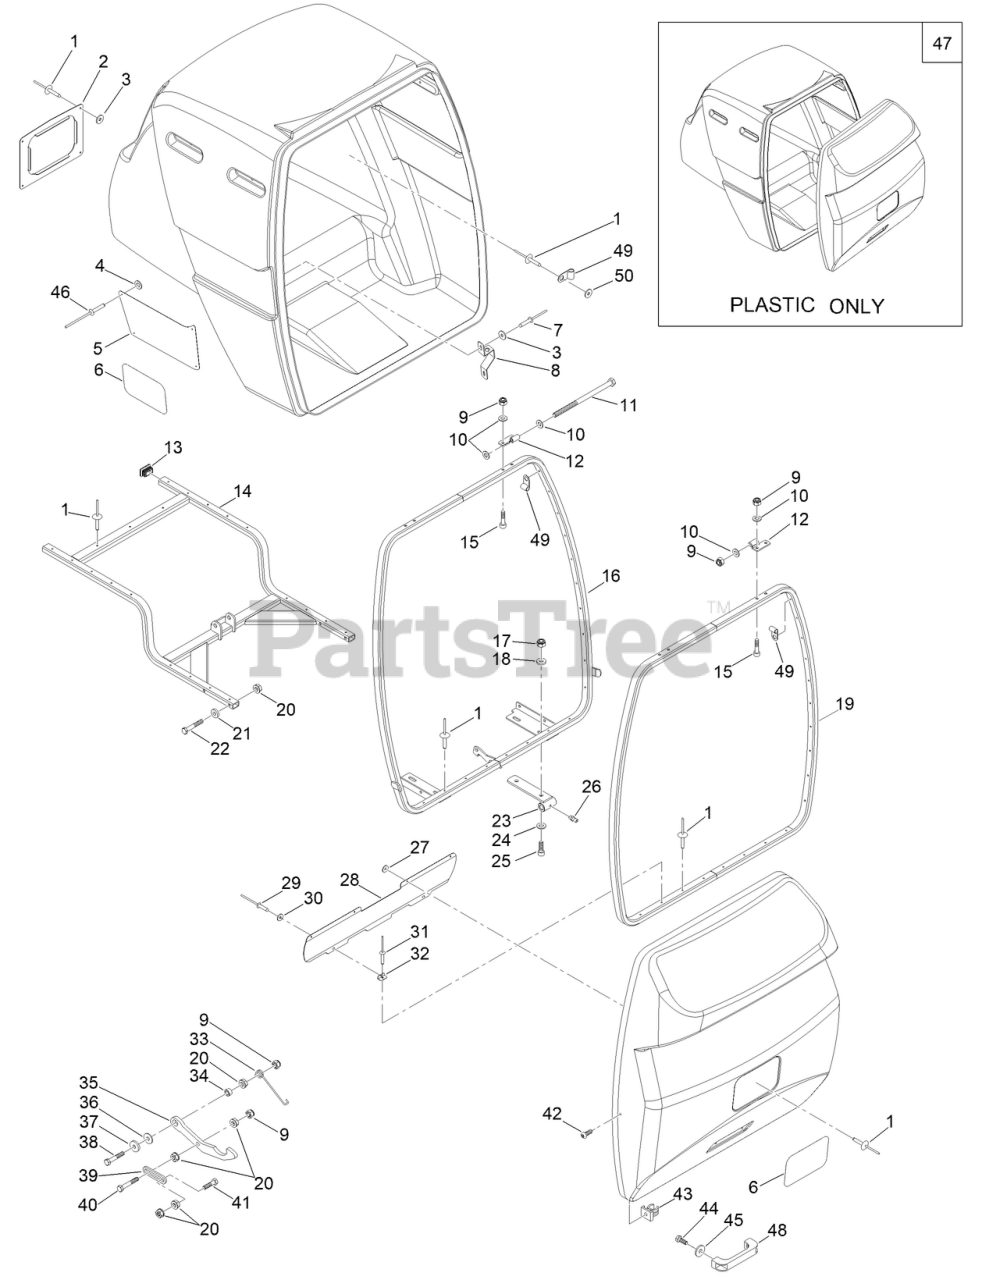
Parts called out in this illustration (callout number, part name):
2	FLANGE, CHUTE COUPLING
3	WASHER
4	WASHER
5	PLATE-LOGO, HOPPER
8	BRACKET
10	WASHER
13	CAP-PLASTIC, BLACK
14	CHASSIS, HOPPER
16	FRAME, HOPPER
18	WASHER
19	FRAME, HOPPER DOOR
21	WASHER
22	SCREW-HH
23	FRAME, HOPPER BODY
24	WASHER
25	SCREW-HSH
26	FITTING-GREASE
27	WASHER
28	SLIDE, HOPPER DOOR
30	WASHER
32	BRACKET
33	SPRING
34	SPACER
35	HOOK, HOPPER DOOR
36	WASHER
37	WASHER-PLAIN
39	SCREW-HH
40	RING, HOPPER HOOK
43	COLLAR
45	WASHER
47	HOPPER, CUT AND DRILLED
48	HANDLE
49	GROMMET
50	WASHER
